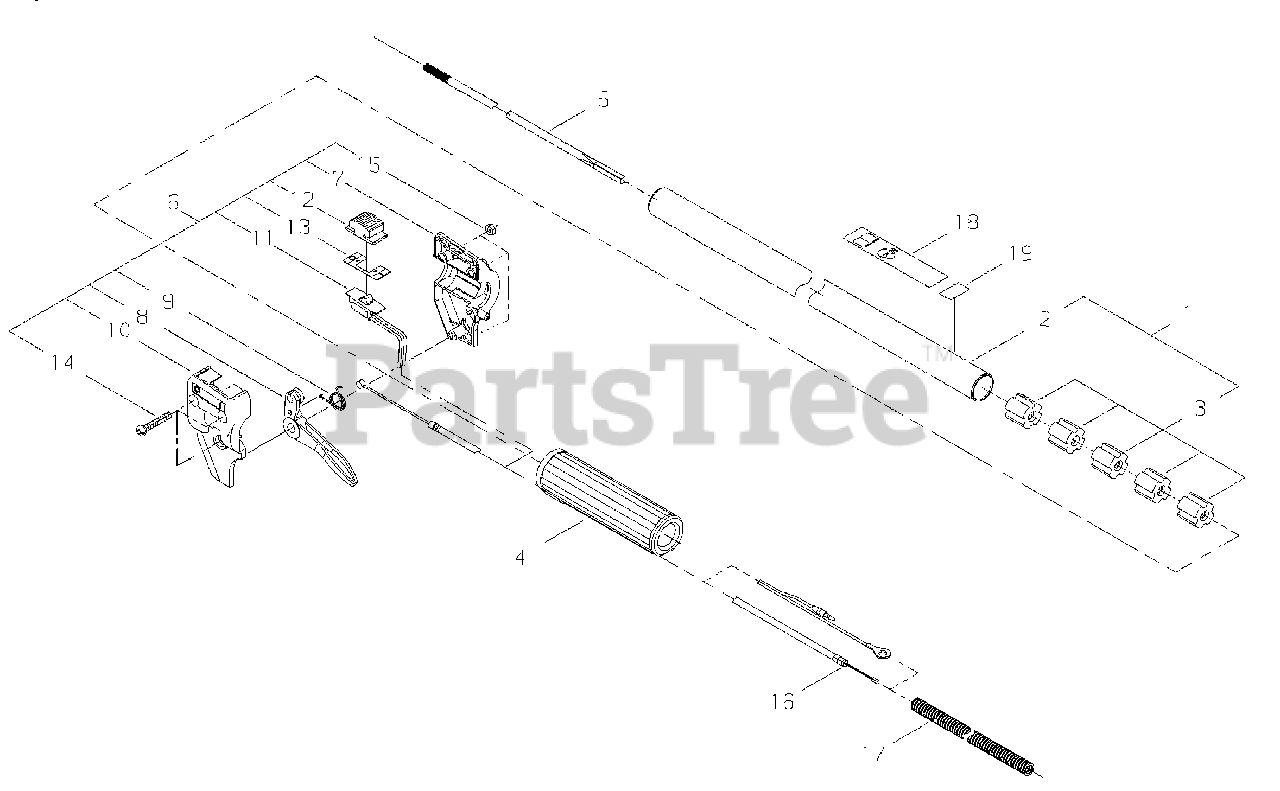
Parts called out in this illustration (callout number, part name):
1	MAIN PIPE ASSY
2	PIPE, MAIN
3	BUSHING
4	GRIP
5	DRIVESHAFT - FLEXIBLE
6	THROTTLE LEVER ASSY
7	BRACKET - RIGHT
8	TRIGGER, THROTTLE
9	SPRING, TRIGGER
10	BRACKET - LEFT
11	SWITCH, IGNITION
12	KNOB
13	PLATE, SWITCH
14	SCREW - 5X30
15	NUT - 5
16	CABLE, THROTTLE
17	TUBE
18	LABEL - CAUTION
19	LABEL - INSTRUCTION
